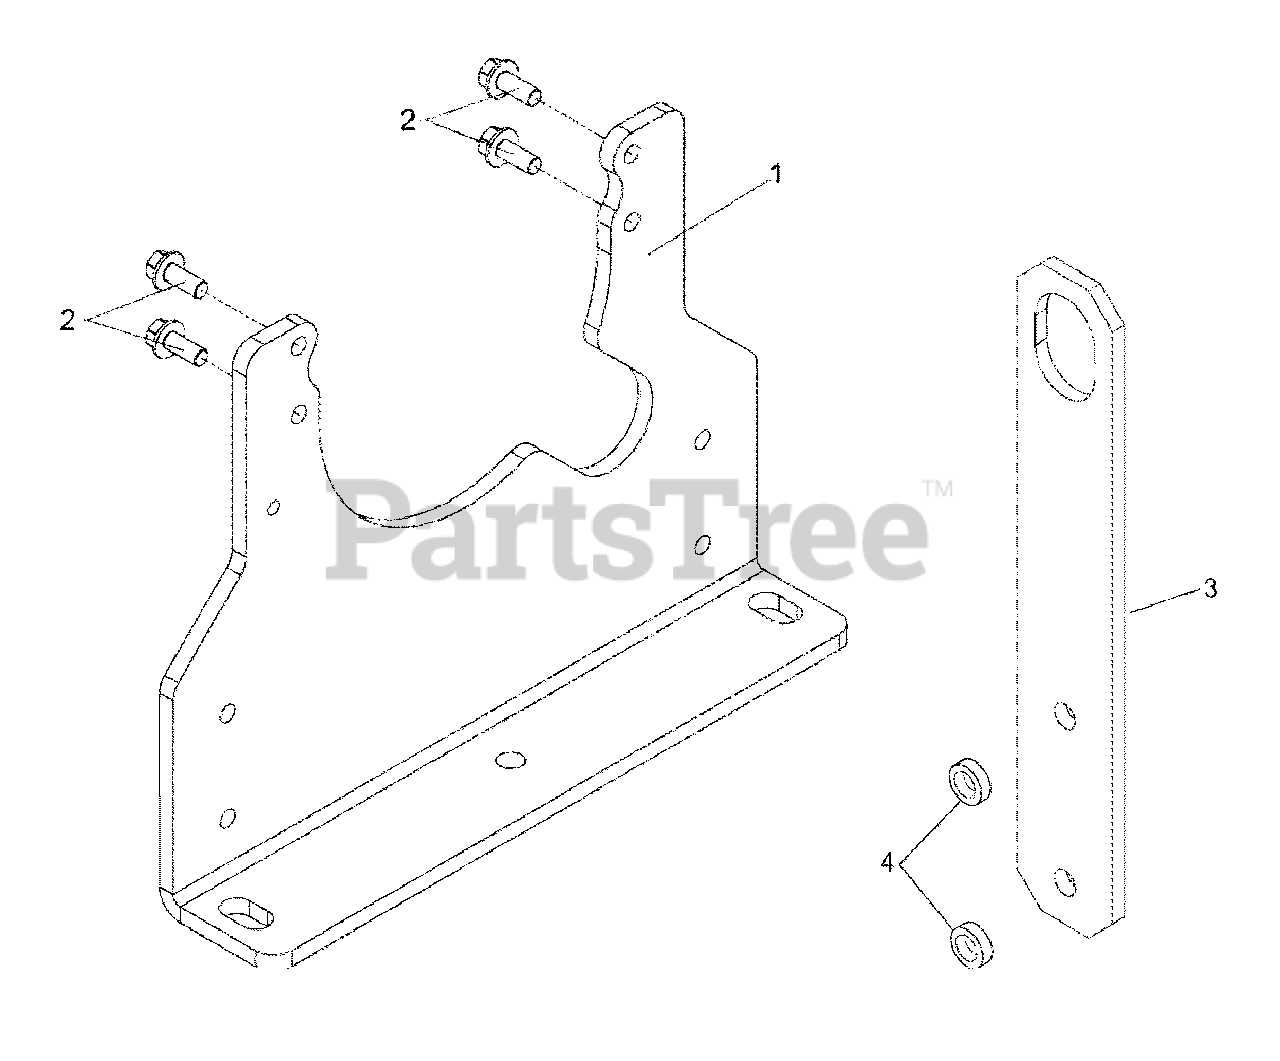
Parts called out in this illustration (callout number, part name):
1	BRACKET
2	SCREW
3	BRACKET
4	SPACER
